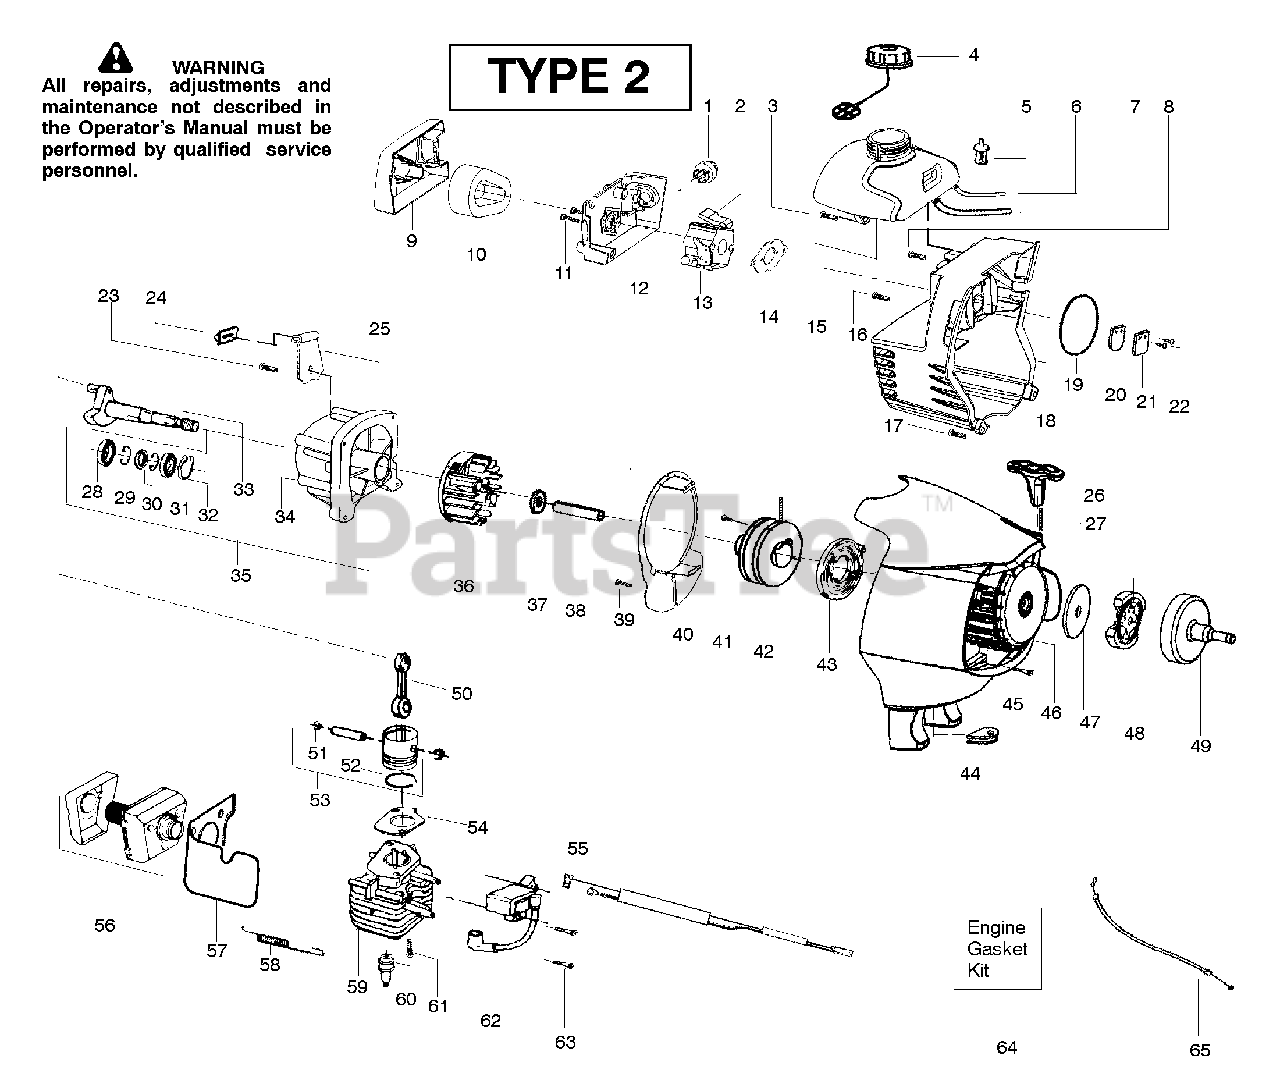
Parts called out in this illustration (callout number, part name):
1	Bulb-Purge
2	Kit-Choke Lever
3	Screw-tank
4	Cap-Fuel w/ret.
5	Assy-Fuel pickup
6	Kit-Fuel line
7	Kit-Fuel/Purge line
9	Cover-Air box
10	Filter-Air
11	Screw-Carb.
13	Assy-Carb (WT628)
14	Gasket-Carb. (kit)
15	Assy-Fuel Tank
16	Screw-Crankcase
17	Screw-Shroud
19	O-ring-Shroud (kit)
20	Valve-Reed
21	Stop-Reed
22	Screw-Reed stop
23	Screw-Retainer
24	Isolator-Tank
25	Ret.-Tank
26	Handle-Starter
27	Kit-Rope
28	Bearing-Inner
29	Retainer
31	Bearing-Outer
32	Ret.-Crankshaft
33	Assy-Crankshaft
34	Assy-Crankcase
35	Assy-C'case/C'shaft
36	Assy-Flywheel
39	Screw-Baffle
40	Plate-Baffle
41	Screw-Rope
42	Kit-Pulley
43	Spring-Starter
45	Screw-F/hsg.
46	Assy.-Fan Housing
47	Washer-Clutch
48	Assy-Clutch
49	Drum-Clutch
50	Assy-Conn. Rod
51	Ret.-Piston pin
52	Ring-Piston
53	Kit-Piston
54	Gasket-Cylinder (kit)
55	Assy-Leadwire
56	Kit-Muffler
58	Spring-Muffler
59	Kit-Cylinder
60	Plug-Spark (RCJ-6Y)
61	Bolt-Cyl. 1/4-20"
62	Module-Ignition
63	Screw-Module
64	Kit-Gasket
65	Assy-Throttle cable
